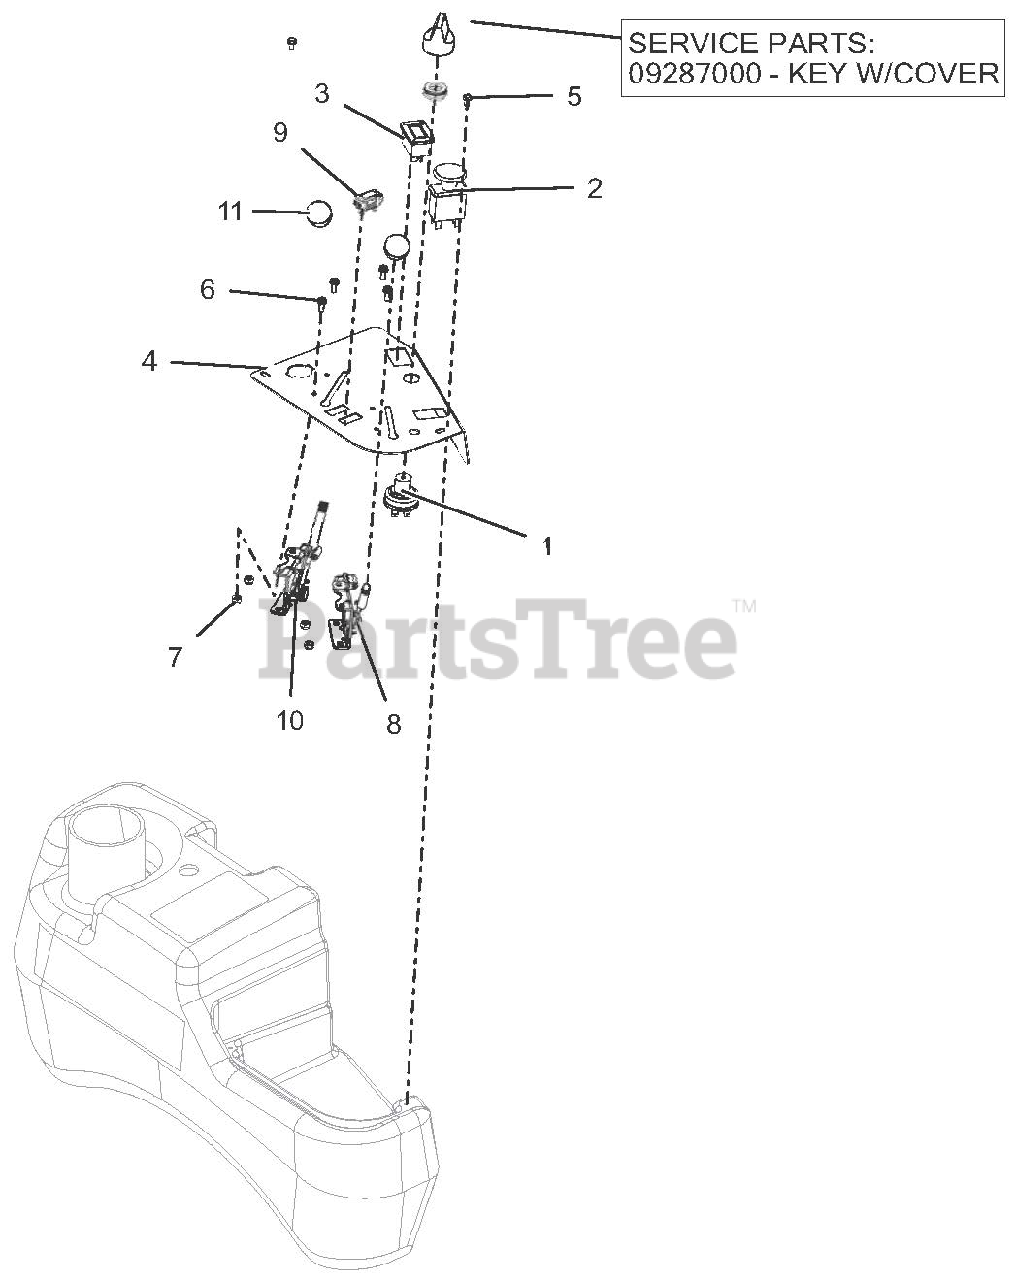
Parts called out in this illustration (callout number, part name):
1	SWITCH, IGNITION
2	SWITCH, CLUTCH
3	METER, HOUR W/MAINTENANCE
4	PANEL, CONTROL - PROTURN 100
5	SCR-MCH 10-24X.38 HWHSTAINLESS
6	@SCR-MCH 10-24X.50 HWH YWZC
7	NUT-LK-NYL #10-24 YWZC
8	CABLE, THROTTLE 53"
9	LIGHT, INDICATOR
10	CABLE, PRO-CONTROL THROTTLE
11	KNOB, CONTROL BLACK .38-16X.50
12	KEY W/COVER
